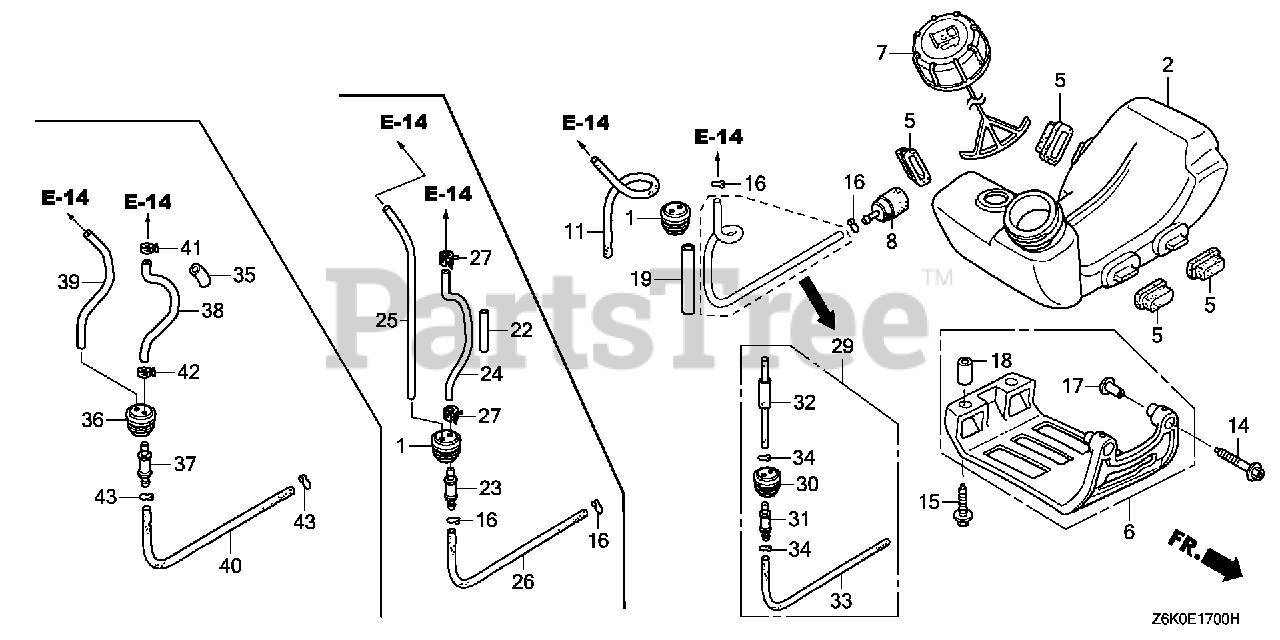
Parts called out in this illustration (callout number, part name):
1	GROMMET, FUEL TUBE
2	TANK, FUEL (COO)
2	TANK, FUEL (FOR U.S.A.)
2	TANK, FUEL
5	RUBBER, TANK MOUNTING
7	CAP ASSY., FUEL TANK
8	FILTER, FUEL
11	TUBE, FUEL RETURN
16	CLIP, TUBE
22	PROTECTOR, TUBE
23	JOINT, FUEL TANK
24	TUBE, FUEL
25	TUBE, FUEL RETURN
26	TUBE A, FUEL
27	CLAMP, TUBE
29	GROMMET ASSY., FUEL TANK
30	GROMMET, FUEL TUBE
31	FITTING
32	TUBE, FUEL FEED
33	TUBE A, FUEL
34	CLIP, TUBE
